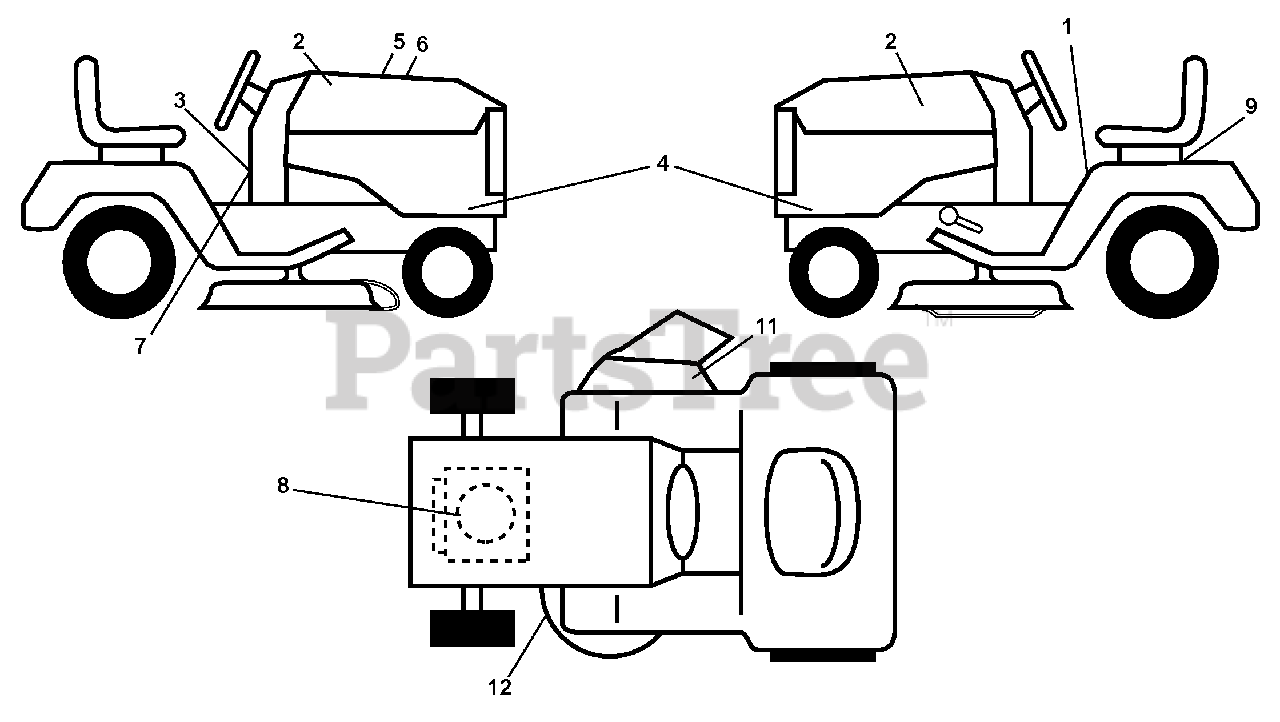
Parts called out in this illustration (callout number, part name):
1	Decal, Fender Warn./Instructions
2	Decal, Badge Logo
3	Decal, Warning Spark Arrestor
4	Decal, Hood Panel
5	Decal, Customer Respons.
6	Decal, Replacement
7	Label Emiss. CA.
8	Decal, Engine
9	Decal, Battery Dnge/Poi
11	Decal, Warning
12	Decal, Mower V-Belt Schematic
